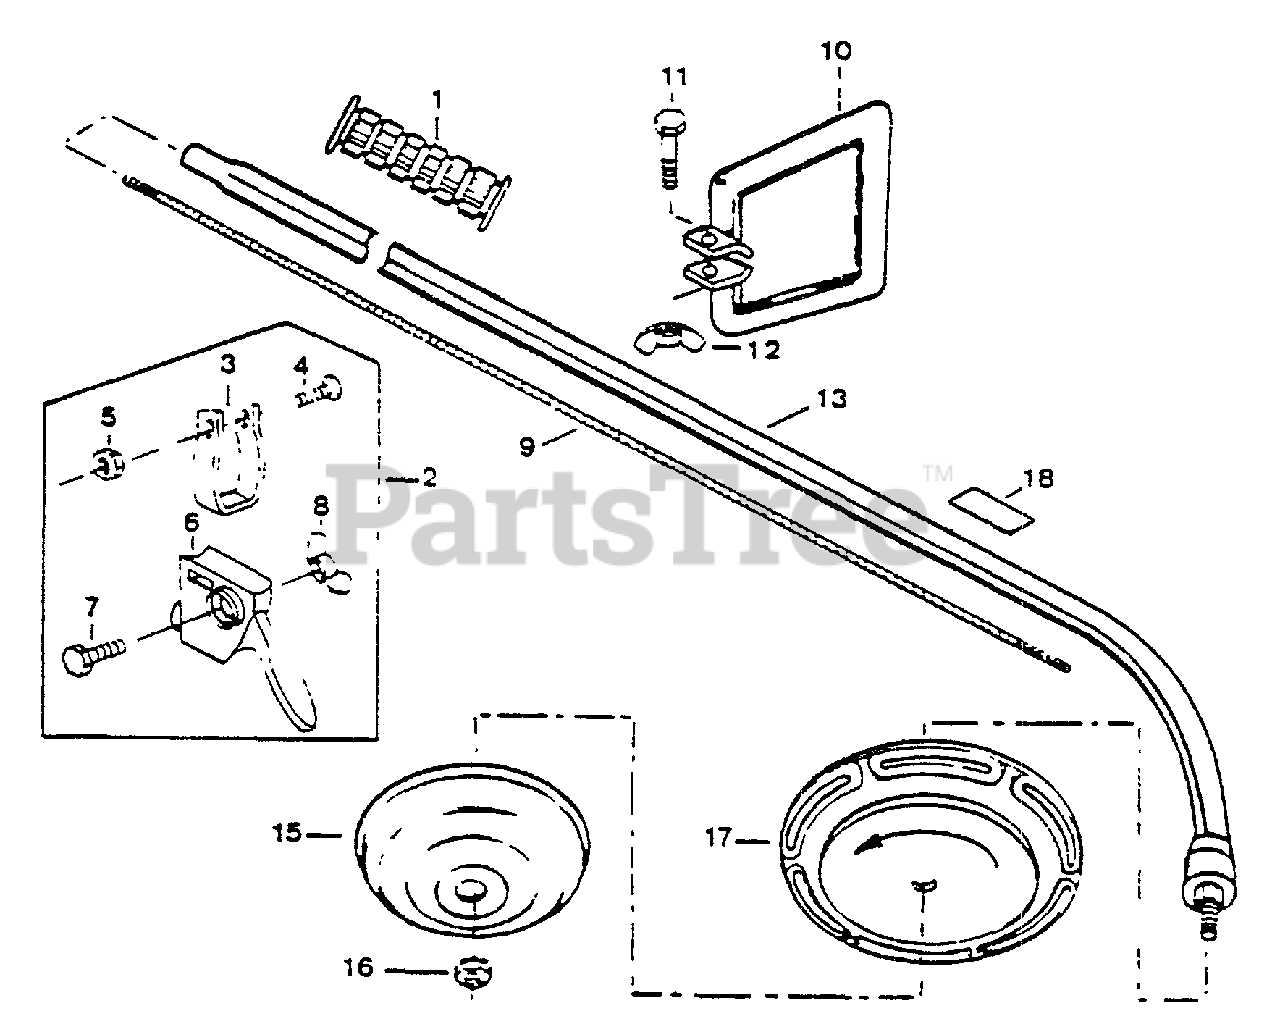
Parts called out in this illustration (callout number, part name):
2	CONTROL CABLE ASSY
3	CLAMP, THROTTLE
4	SCREW - 10-32 -- PAN HEAD
5	NUT - 10-32
6	LEVER THROTTLE W/BODY
7	SCREW - 10-32×1"
8	WINGNUT - 50-32
9	DRIVESHAFT - FLEXIBLE
10	GUIDE HANDLE
11	SCREW - 1/4-20 -- HEX HEAD
12	WINGNUT - 1/4-20
13	DRIVESHAFT ASSY - LEFT
14	MONO-HEAD W/0.080 LINE COMPLETE
15	LID
16	SCREW - 1/4-20
17	HEAD BODY MONO-HEAD
18	LABEL - LUBRICATION
